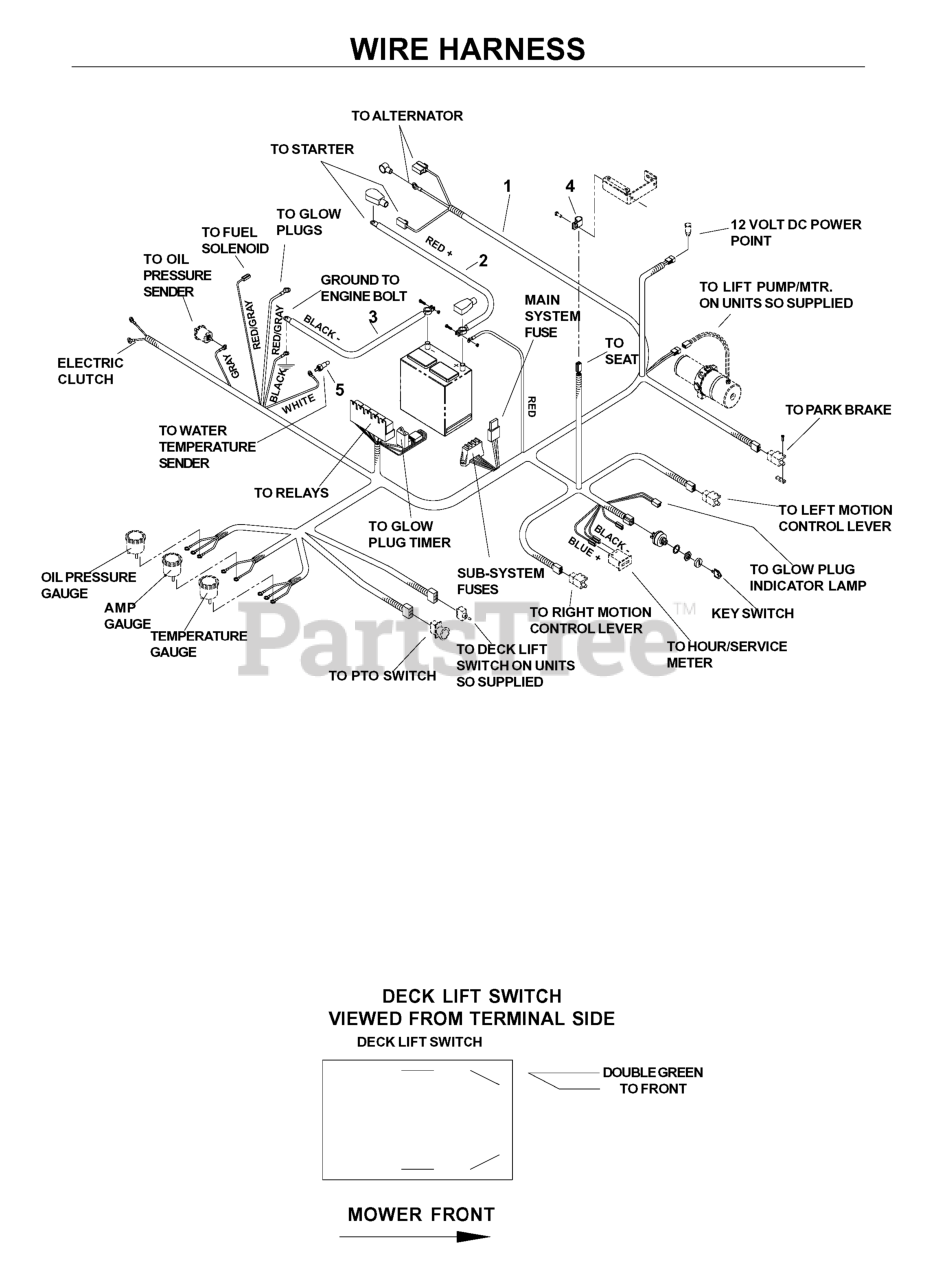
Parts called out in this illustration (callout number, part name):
1	HARNESS, ENG - B&SD DIESEL
2	CABLE, POS.
3	CABLE, NEG.
5	SENDER,TEMP
